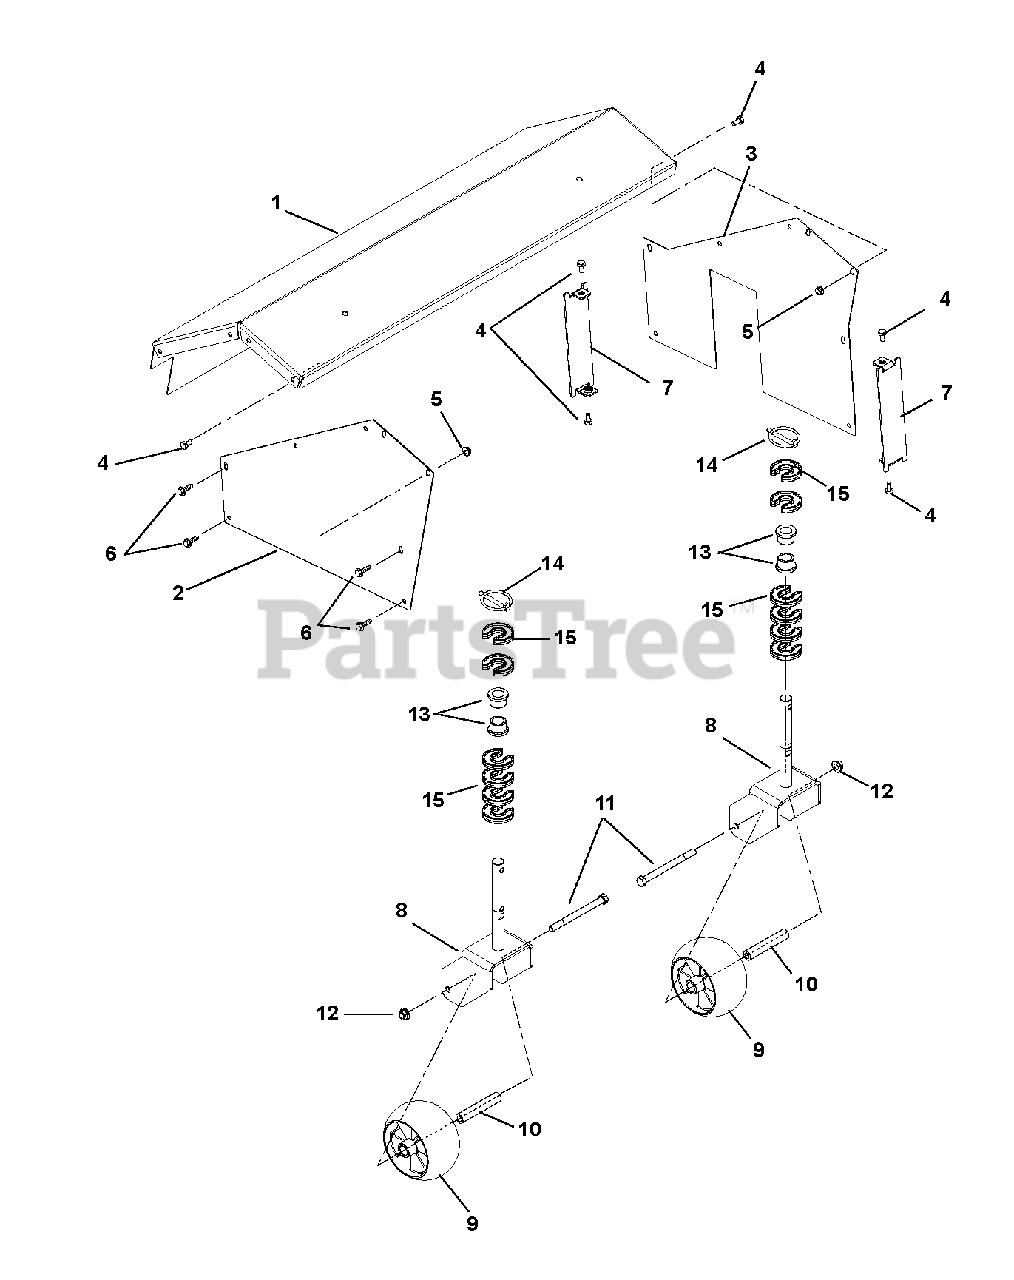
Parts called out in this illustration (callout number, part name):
1	Cover with Decals, 28" Brush
2	Cover, Right Hand Side
3	Cover, Left Hand Side
4	Bolt, Hex .25-20 x .50
5	Nut, Locking Top Flange .25-20
6	Screw, Tapping Hex Washer Head Thread Rolling .25-20 x .50
7	Cover, End
8	Fork, Caster
9	Wheel, Anti-Scalp
10	Spacer, Caster Wheel
11	Bolt, Hex .38-16 x 4.50
12	Nut, Locking Top Flange .38-16
13	Bushing, Flange
14	Pin, Lynch .25 x 1.25
15	Clip, HOC
